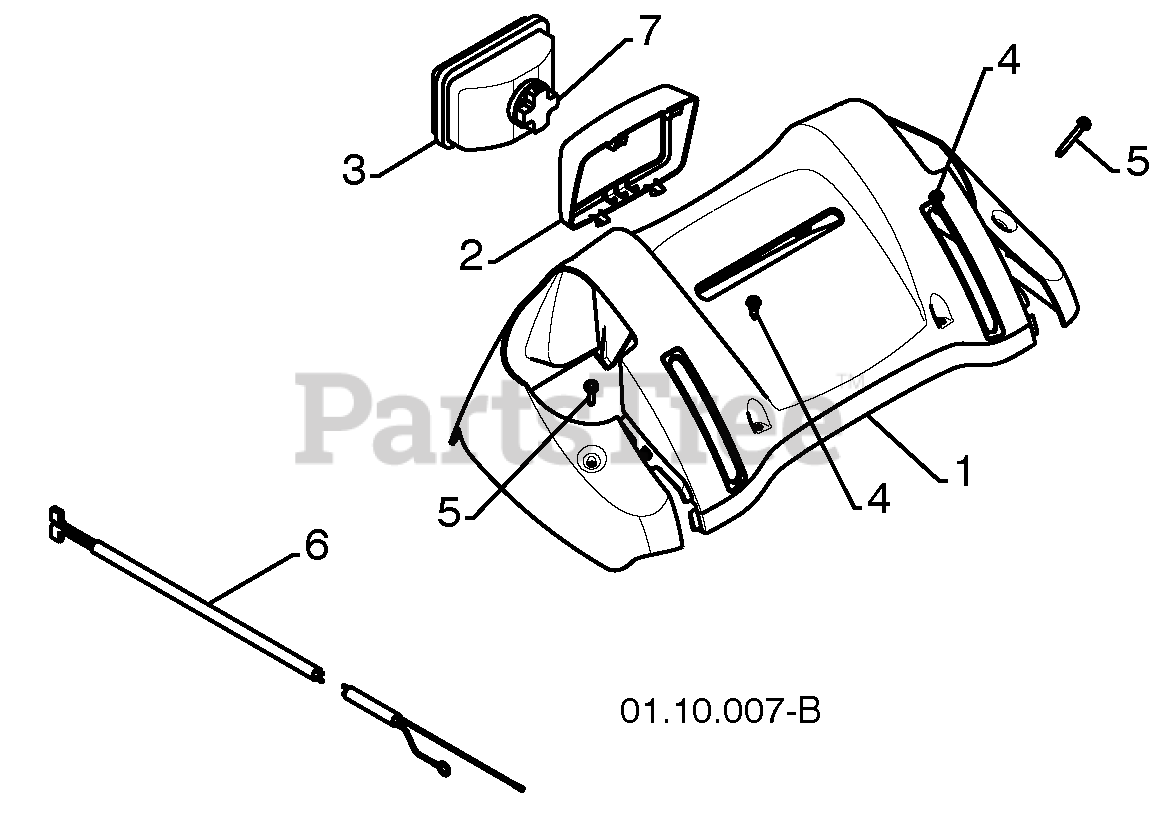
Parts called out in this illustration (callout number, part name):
1	CONSOLE PANEL
2	HEADLIGHT BEZEL
3	FLOOD HEADLIGHT
4	SHOULDER SCREW 10-24 X .625
5	SCREW 10-24 X 1.25
6	WIRE HARNESS
7	BULB
